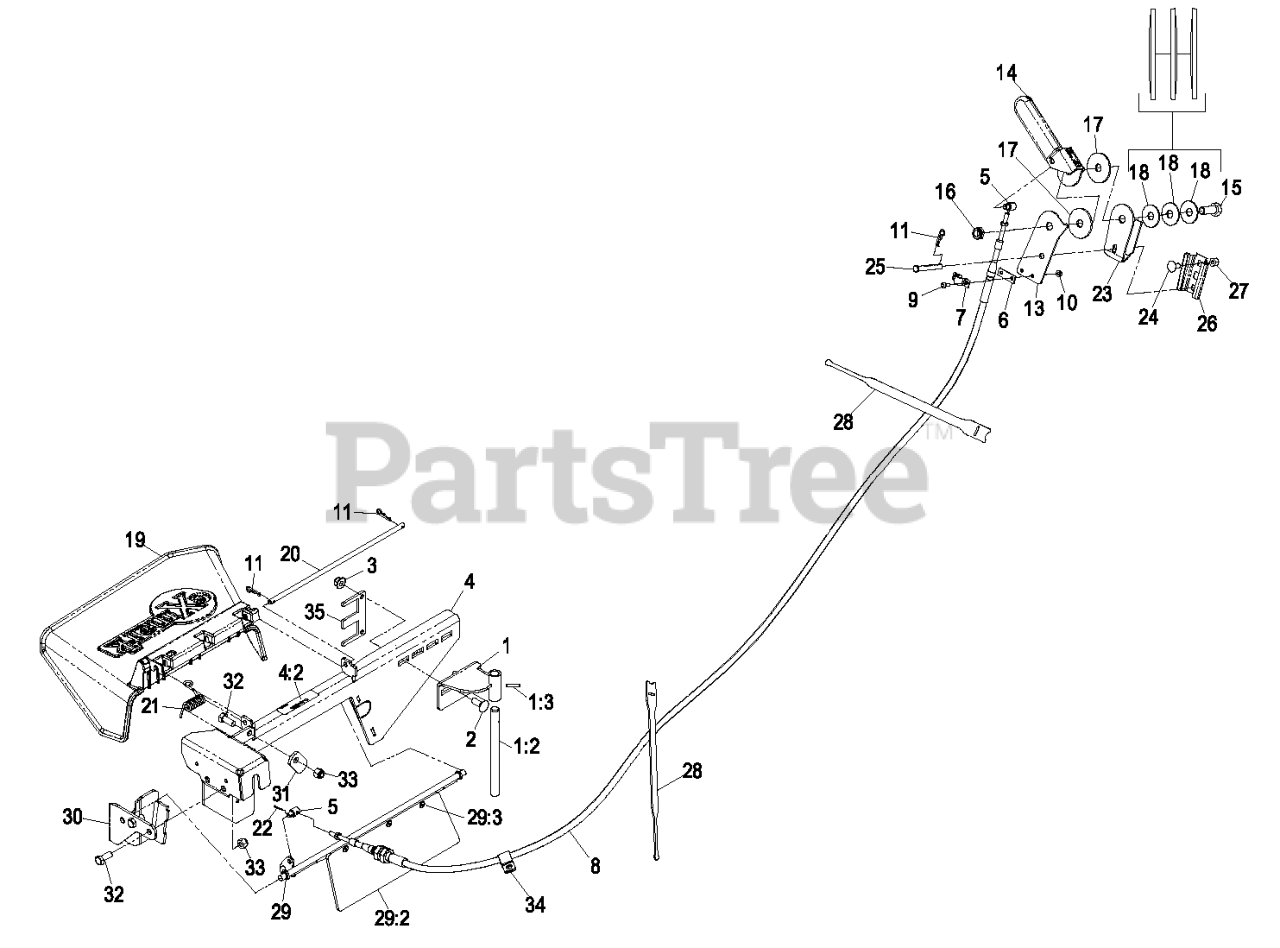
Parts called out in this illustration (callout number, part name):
1	ASM,OCD MOUNT
1:2	SHAFT-CATCHER, GRASS
1:3	PIN-ROLL
2	BOLT-CARR
3	NUT-HF, NI
4	GATE,LINK FRAME
4:2	DECAL-COVER, MISSING
5	PIVOT,CONTROL CABLE
6	SHIM,CONTROL CABLE
8	CABLE-DISCHARGE GATE
9	SCREW-PPH
10	NUT-LOCK, NI
11	PIN-COTTER
13	BRACKET,CONTROL MOUNT
14	CONTROL HANDLE ASM-OCD
15	SCREW-HH
16	NUT-HEX
17	DISC-FRICTION
18	WASHER-DISC, SPRING
19	CHUTE DEFLECTOR XRK M056
20	PIN,CHUTE
21	SPRING, TORSION
22	PIN-COTTER
23	BRACKET,HANDLE MOUNT
24	SCREW-CARR
25	PIN-CLEVIS
26	BRACKET-MOUNTING,SMV
27	NUT-LOCK, NI
28	STRAP-VELCRO, CABLE TIE
29:2	GATE,OCDCWB
29:3	RIVET-BLIND
30	BRKT,CHUTE FRONT
31	LATCH-CATCHER, GRASS
32	SCREW-HH
33	NUT-LOCK, NI
34	CLIP-LOOM
